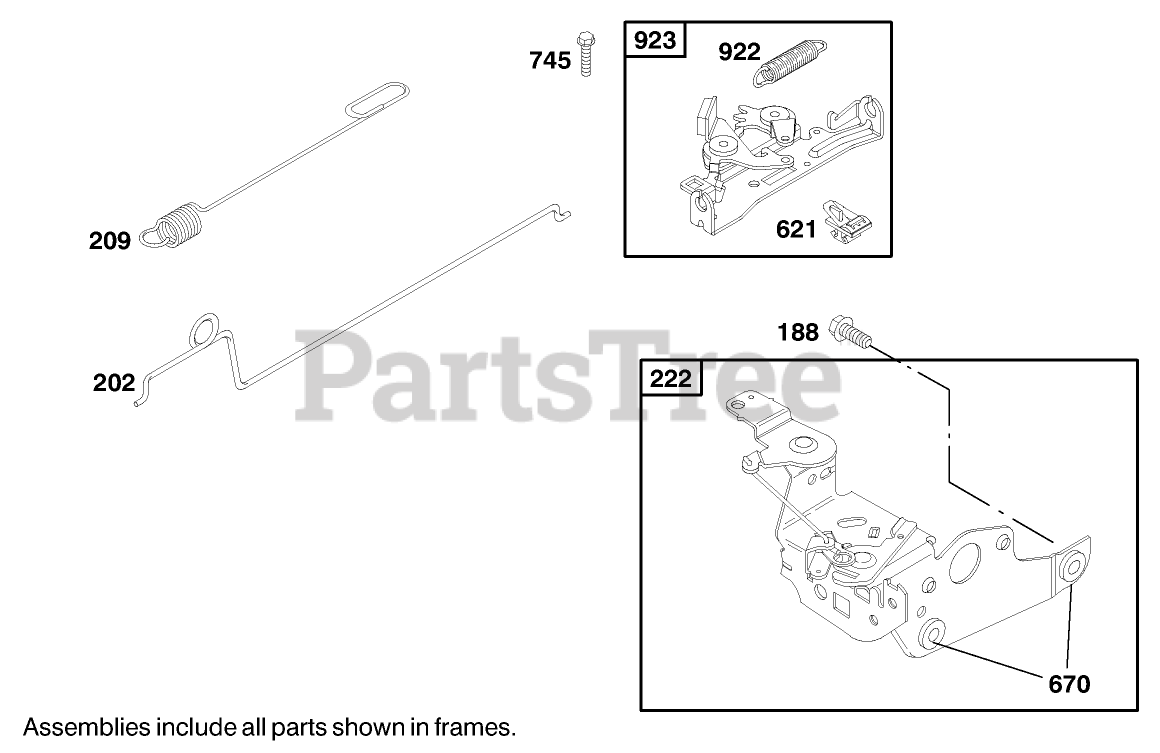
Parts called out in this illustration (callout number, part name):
188	Screw
202	Link-Govemor
209	Spring-Governor
222	Carburetor Bracket
621	Switch
670	Spacer
745	Screw-Sem
922	Brake Spring
923	Brake
